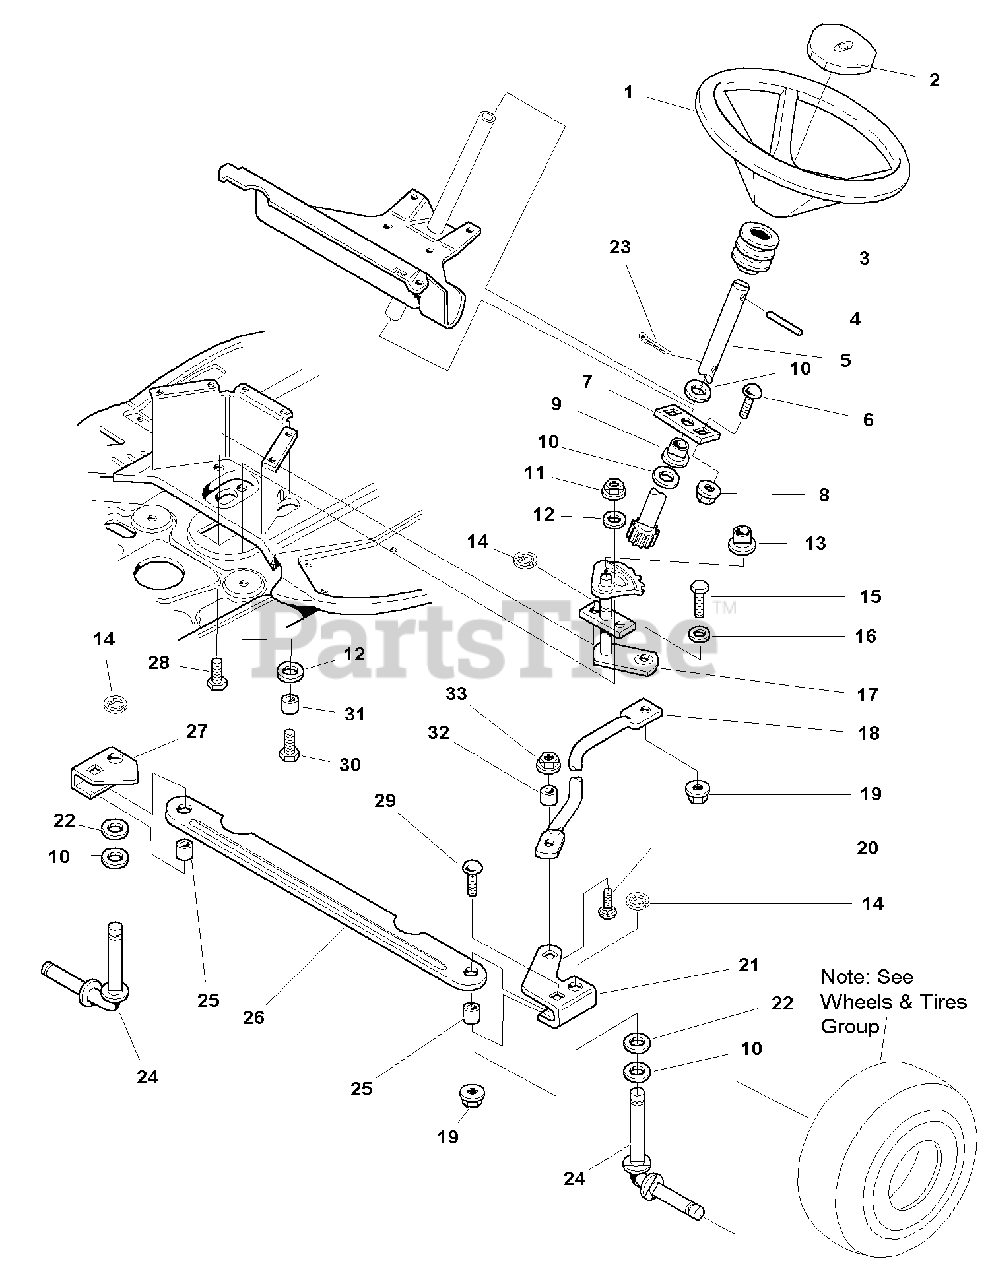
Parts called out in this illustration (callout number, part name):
1	STEERING WHEEL
2	CAP, Steering Wheel, Simplicity
3	TUBE, Cover
4	PIN, Spring
5	SHAFT & PINION ASSEMBLY
6	CARRIAGE BOLT, 3/8-16 x 1
7	PLATE, Mounting
8	NUT, Hex Whiz Lock, 3/8-16
9	BUSHING, 3/4, Nylon
10	WASHER, 3/4
11	NUT, Hex Lock, 5/16-18
12	WASHER, 5/16
13	BUSHING, 3/4, Powered Metal
14	RING, Clipring Extension
15	CAPSCREW, Hex Head, 3/8-16 x 1-1/4
16	WASHER, 3/8
17	SHAFT & GEAR ASSEMBLY
18	LINK, 19.66" Long
19	NUT, Hex Flange Lock, 3/8-16
20	CARRIAGE BOLT, 5/16-18 x 1
21	ARM & SPACER ASSEMBLY, LH Splined
22	WASHER, 3/4
23	PIN, Cotter
24	SPINDLE & CUP ASSEMBLY
27	ARM & SPACER ASSEMBLY, RH Splined
28	CAPSCREW, Hex Head Taptite, 5/16-18 x 3/4
29	CARRIAGE BOLT, 3/8-16 x 1-1/4
30	CAPSCREW, Hex Head, 5/16-18 x 1-1/2
33	NUT, Hex Flange Lock, 5/16-18
